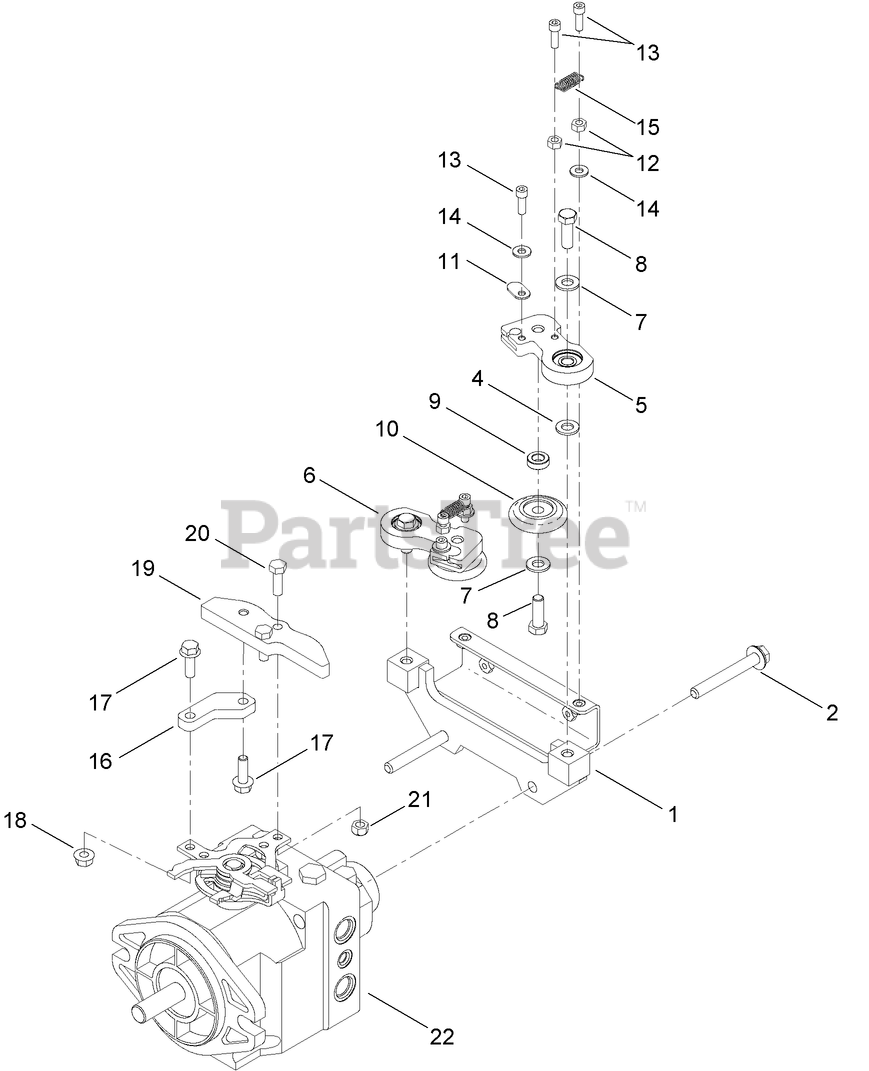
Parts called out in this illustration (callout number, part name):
1	BRACKET-CONTROL, PUMP
2	SCREW-HHF
4	WASHER-FLAT
5	CONTROL-PIVOT RIGHT
6	CONTROL-PIVOT LEFT
7	WASHER-FLAT
8	SCREW-HH
9	SPACER-PIVOT
10	WHEEL-CUTTING, TABLE
11	COVER-END, CABLE
12	NUT-HEX
13	SCREW-HSH
14	WASHER-FLAT
15	SPRING-EXTENSION, CONTROL PUMP
16	PLATE-ARM, CONTROL
17	SCREW-HHF
18	NUT-HF
19	PLATE-PUMP, CONTROL
20	SCREW-HH
21	NUT-LOCK, NI
22	HYD PISTON PUMP ASM
